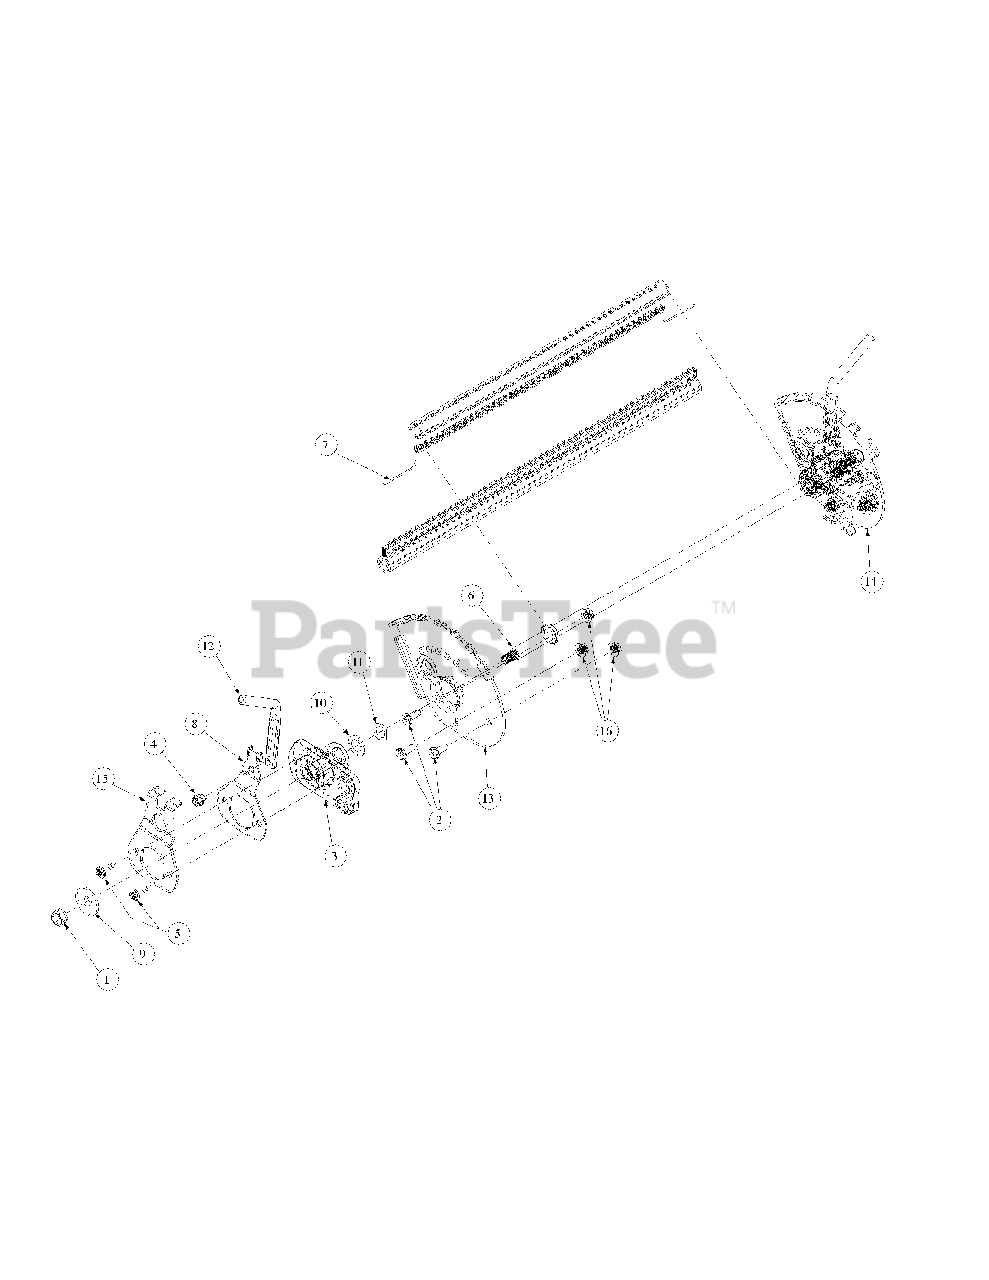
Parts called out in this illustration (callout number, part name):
1	L-Nut, 3/8-16, NYL INS. GR A.
2	HHCS, 1/4-20, .620, GR5, Standard
3	Pivot Wheel Bracket Assembly, 2 POS
4	Screw, TT, 1/4-20, 0.375, Hex Index Washer
5	Screw, TT, 1/4-20, 0.625, PANTRXI
6	Rear Axle
7	Trail Shield
8	Spring Plate Height Adjuster
9	Flat Washer, .411 x 1 .25 x .100
10	Flat Washer .536 IDX .781 ODX .01
11	Wave Washer .531 IDX .781 ODX .01
12	Height Adjustment Handle
13	Height Adjustment Bracket, Right Rear
14	Height Adjustment Bracket, Left Rear
15	Spring Lever Support Bracket
16	Nut, 1/4-20, Hex Flange, Lock, Group F
